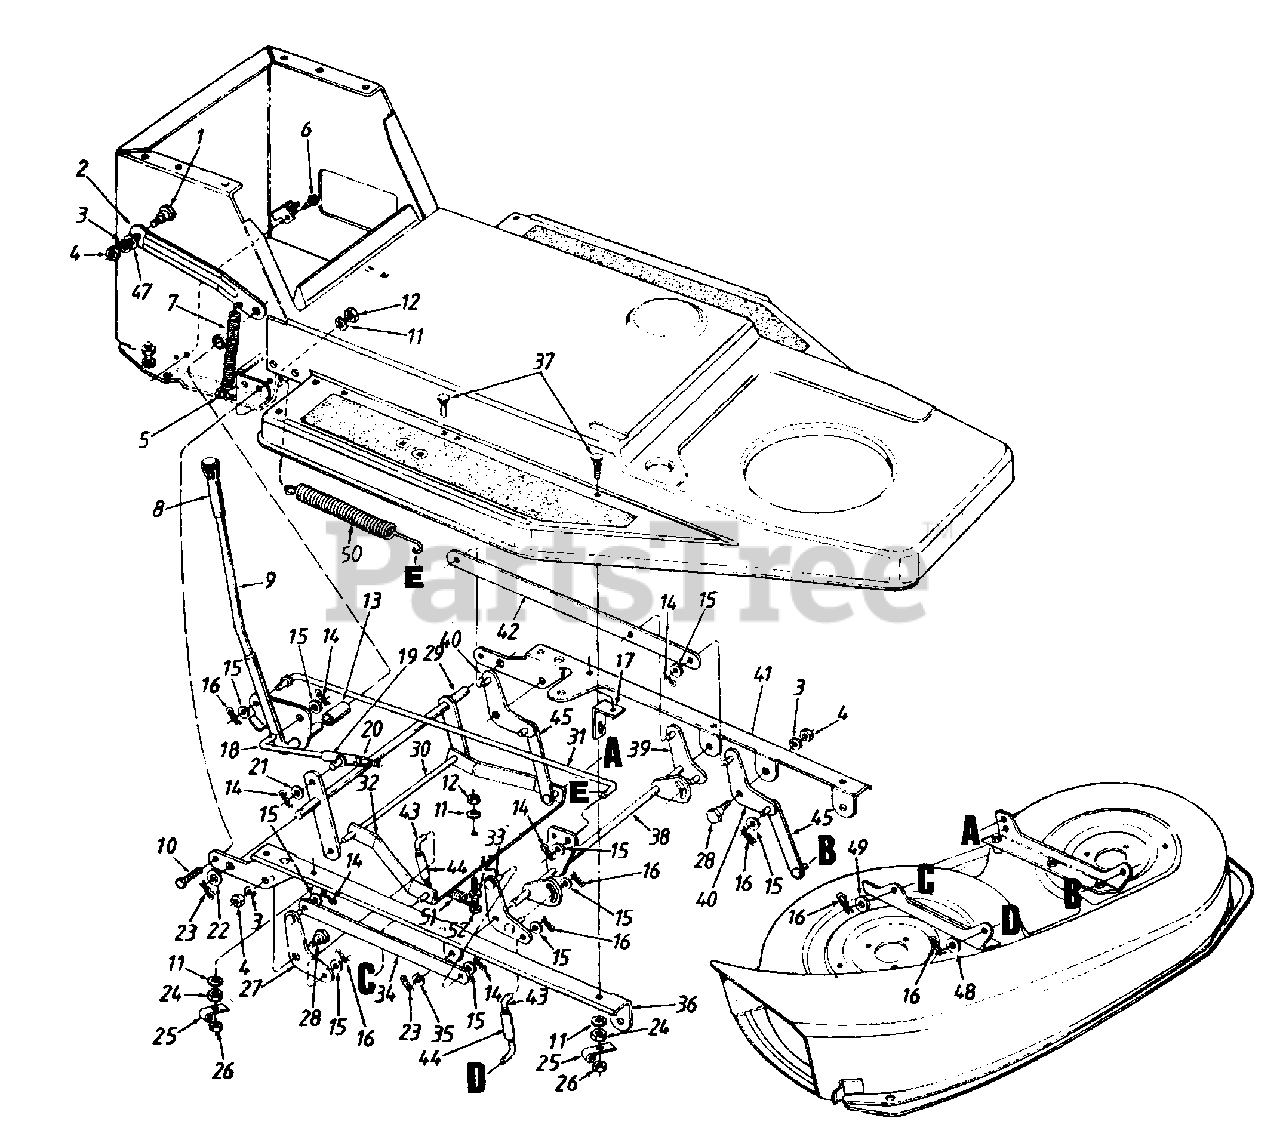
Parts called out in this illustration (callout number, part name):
1	Shoulder Bolt .5" Dia. x .34" Lg.
4	Hex Nut 3/8-16 Thd.
5	Hex Bolt 1/4-28 x 1.25" Lg.
6	Hex TT-Tap Scr. 1/4-20 x .5" Lg.
7	External Spring
8	Grip
9	Deck Lift Handle Ass'y.
10	Hex Washer TT-Tap Scr.
11	Lock Washer 5/16" I.D.
12	Hex Nut 5/16-18 Thd.
13	Spacer 5/8" I.D. x .78"
14	Cotter Pin 3/32" Dia. x .75" Lg.
15	Flat Washer .406" I.D. x .75" O.D.
16	Internal Cotter Pin 5/16" Dia.
19	Pivot Sleeve Ass'y.
20	Hex Lock Nut 3/8-16 Thd.
21	Thrust Washer .382" I.D.
22	Flat Washer .635" I.D. x .93" O.D.
23	Cotter Pin 1/8 Dia. x 1.25" Lg.
24	Hex Nut 5/16-24 Thd.
25	Harness Retainer
26	Hex Cent. Lock Nut 5/16-24 Thd.
27	Deck Pivot Brkt. Ass'y. - R.H.
28	Shld. Bolt .625" Dia. x .170" Lg.
31	Deck Lift Rod
44	Adj. Lift Link Ass'y.
45	Deck Lift Link Ass'y.
47	Flat Washer .531" I.D. x .94"
48	Flat Washer .406" I.D. x .75"
49	Flat Washer 3/8" I.D.
50	Ext. Spring .87" Dia.
51	Ext. Spring 11" Lg.
52	Hex Bolt 5/16-18 x 7/8" Lg.
